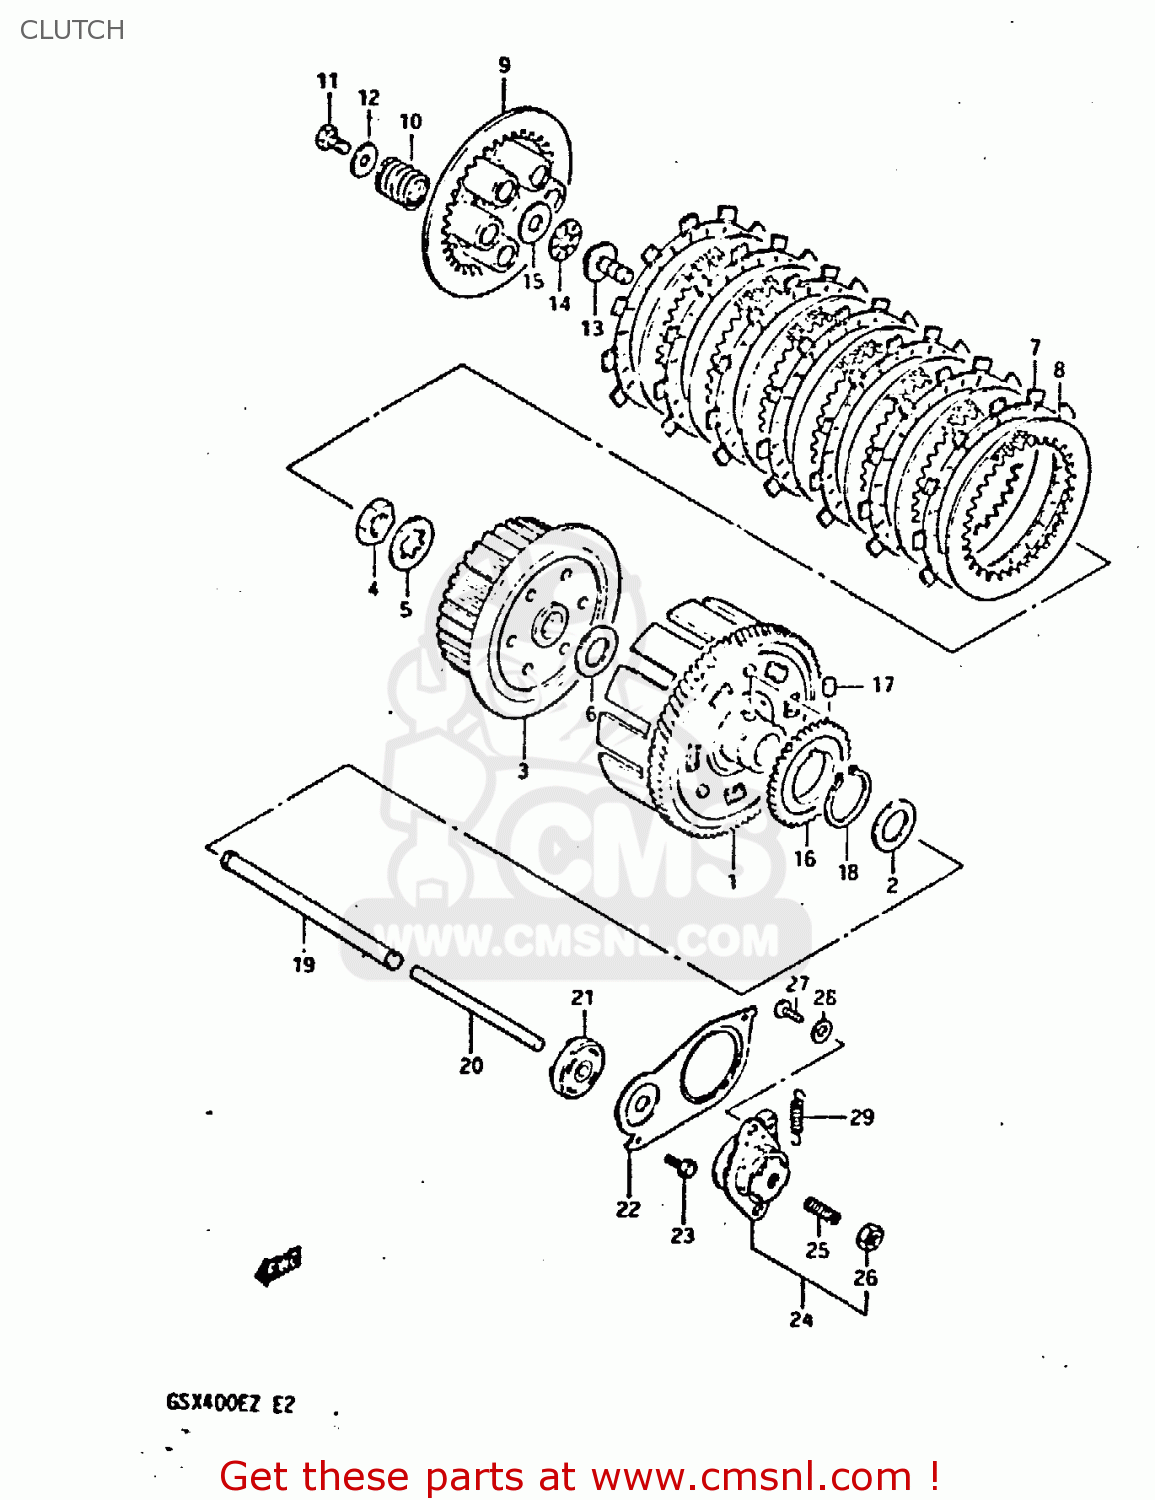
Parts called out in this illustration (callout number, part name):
1	GEAR ASSEMBLY,PRIMARY DRIVE
2	WASHER
3	HUB,CLUTCH SLEEVE
4	NUT (20MM)
5	WASHER,LOCK
6	WASHER(20X44X3)
7	PLATE,CLUTCH DRIVE (MCA)
8	PLATE,CLUTCH DRIVEN (NAS)
9	DISC,CLUTCH PRESSURE
10	SPRING
11	BOLT, UPPER
12	WASHER
13	PIECE,CLUTCH PUSH
14	BEARING(15X28X2)
15	WASHER
16	GEAR,OIL PUMP DRIVE
17	PIN(6X6)
18	CIRCLIP
19	ROD,CLUTCH PUSH
20	ROD,CLUTCH PUSH
21	SEAL,OIL(6X34X10)
22	PLATE,CLUTCH PUSH ROD
23	BOLT
24	SCREW ASSY,CLUTCH RELEASE
25	SCREW
26	NUT 6MM
27	SCREW
28	WASHER
29	SPRING
